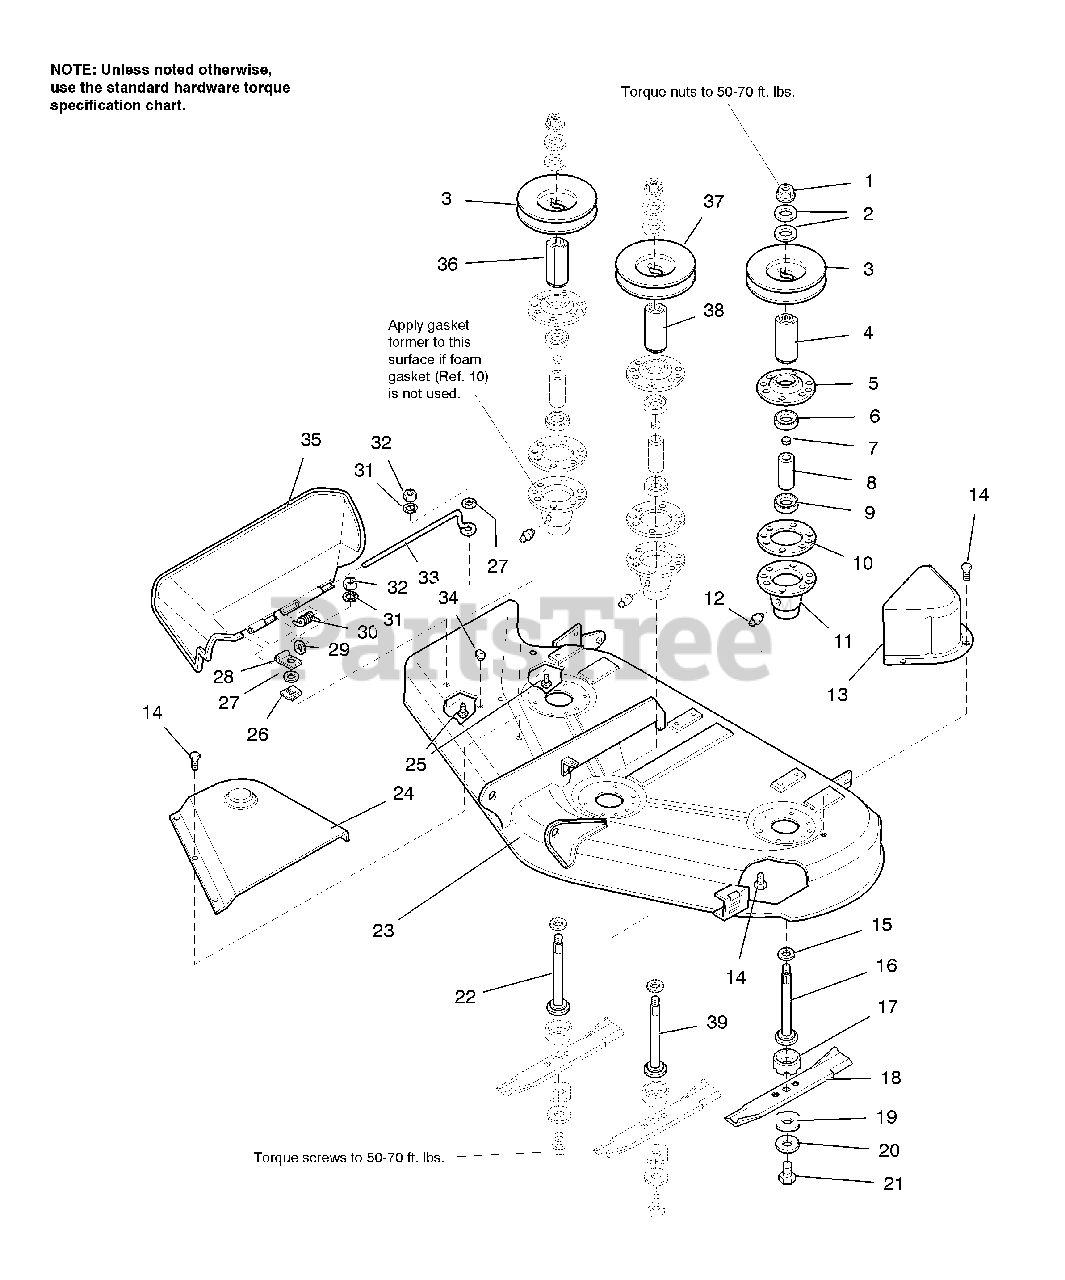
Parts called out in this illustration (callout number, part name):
1	NUT, Hex, Flange, 9/16-8
2	WASHER, Belleville
3	PULLEY,
4	HUB, Adapter (LH)
5	COVER, Arbor Housing
6	BEARING, Upper
7	SPACER, Sleeve, Upper Bearing
8	SPACER, Arbor, Internal
9	BEARING, Lower
10	GASKET, Foam
11	HOUSING ASSEMBLY, Arbor Bottom, w/Lube Fitting
12	FITTING, Grease
13	COVER, Arbor (LH)
14	CAPSCREW, Taptite Hex Washer Hd, 5/16-18 x 3/4
16	SHAFT, Arbor (LH)
17	SHIELD, Grass, Lower
18	BLADE, Mower, 16-1/8
19	WASHER, Hex
20	WASHER, Spring
21	CAPSCREW, Hex, Hd., 7/16-14 x 1-1/4
22	SHAFT, Arbor (RH)
23	HOUSING ASSEMBLY, Orange
23	HOUSING ASSEMBLY, Black
24	COVER, Arbor (RH)
25	CARRIAGE BOLT, 1/4-20 x 7/8
26	NUT, Push On
27	WASHER, Plain, 1/4
29	WASHER, Plain, 5/16
30	SPRING, Deflector Retaining
31	LOCKWASHER, 1/4
32	NUT, Hex, 1/4-20, UNC
33	ROD, Deflector, Front
35	DEFLECTOR, Plastic
36	HUB, Pulley (RH)
37	PULLEY, Arbor (Center)
38	HUB, Pulley (Center)
39	SHAFT, Arbor (Center)
